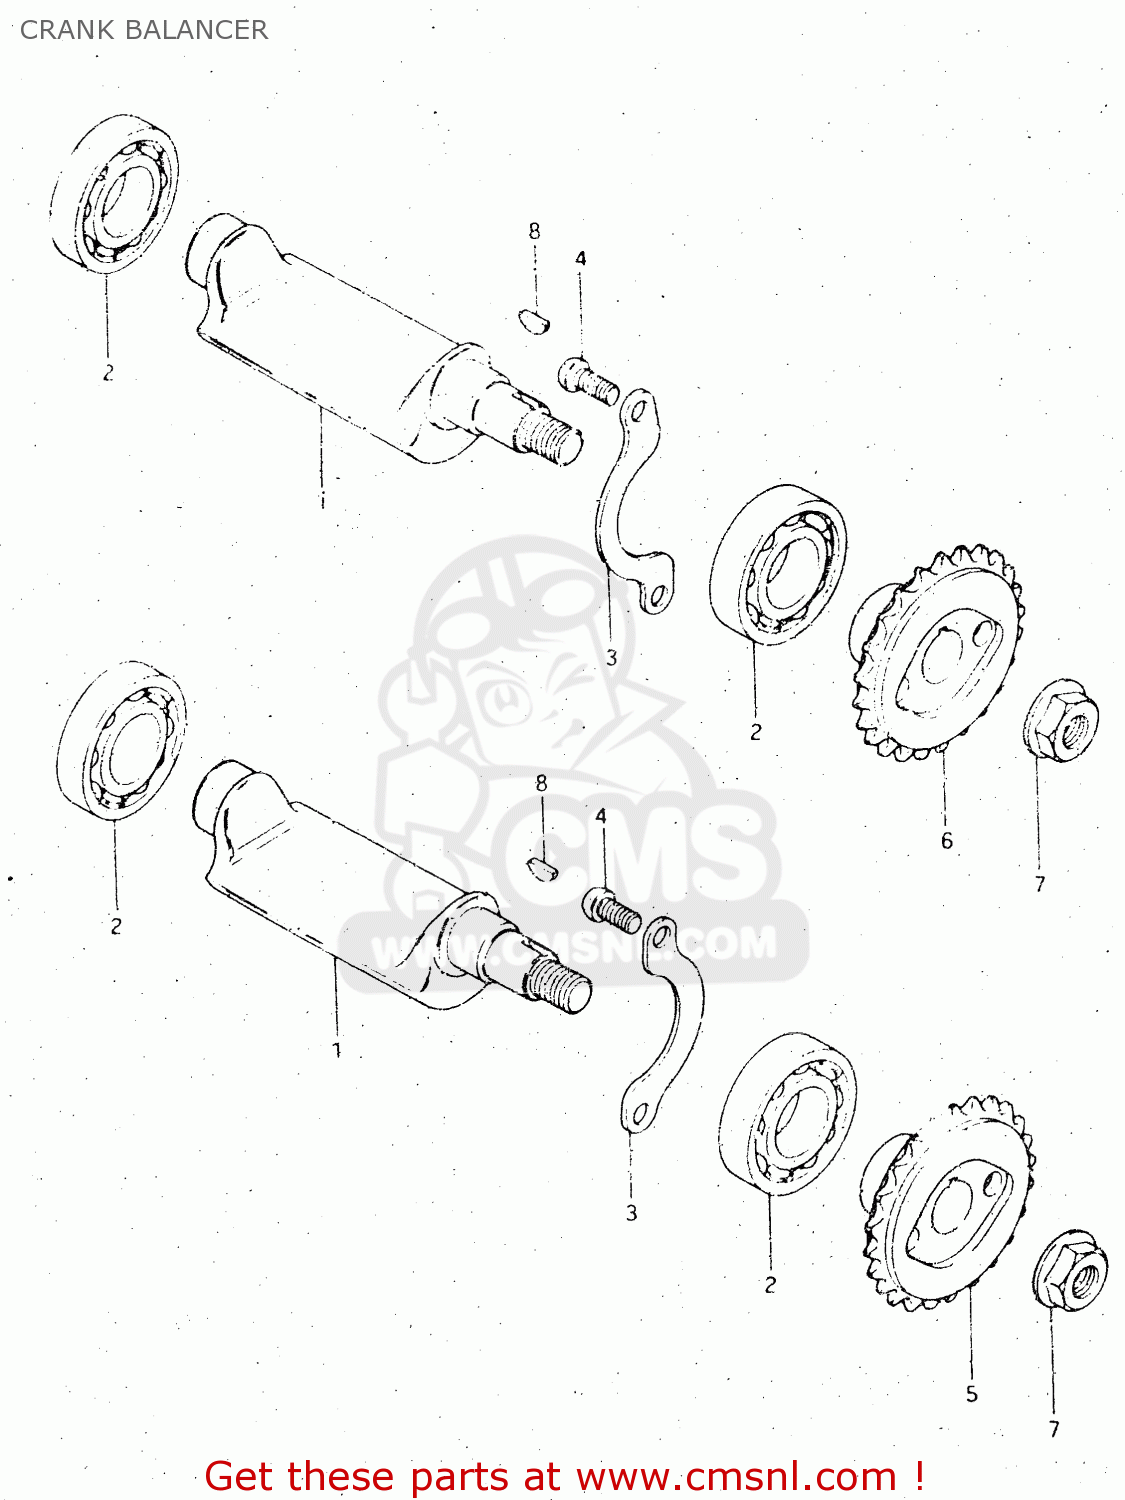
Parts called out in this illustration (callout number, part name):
1	BALANCER,CRANKSHAFT
2	BEARING
3	RETAINER,CRANK BAL BEARING
4	SCREW 6X12
5	SPROCKET,BALANCER DRIVE
6	SPROCKET,BALANCER DRIVE
7	NUT
8	KEY
